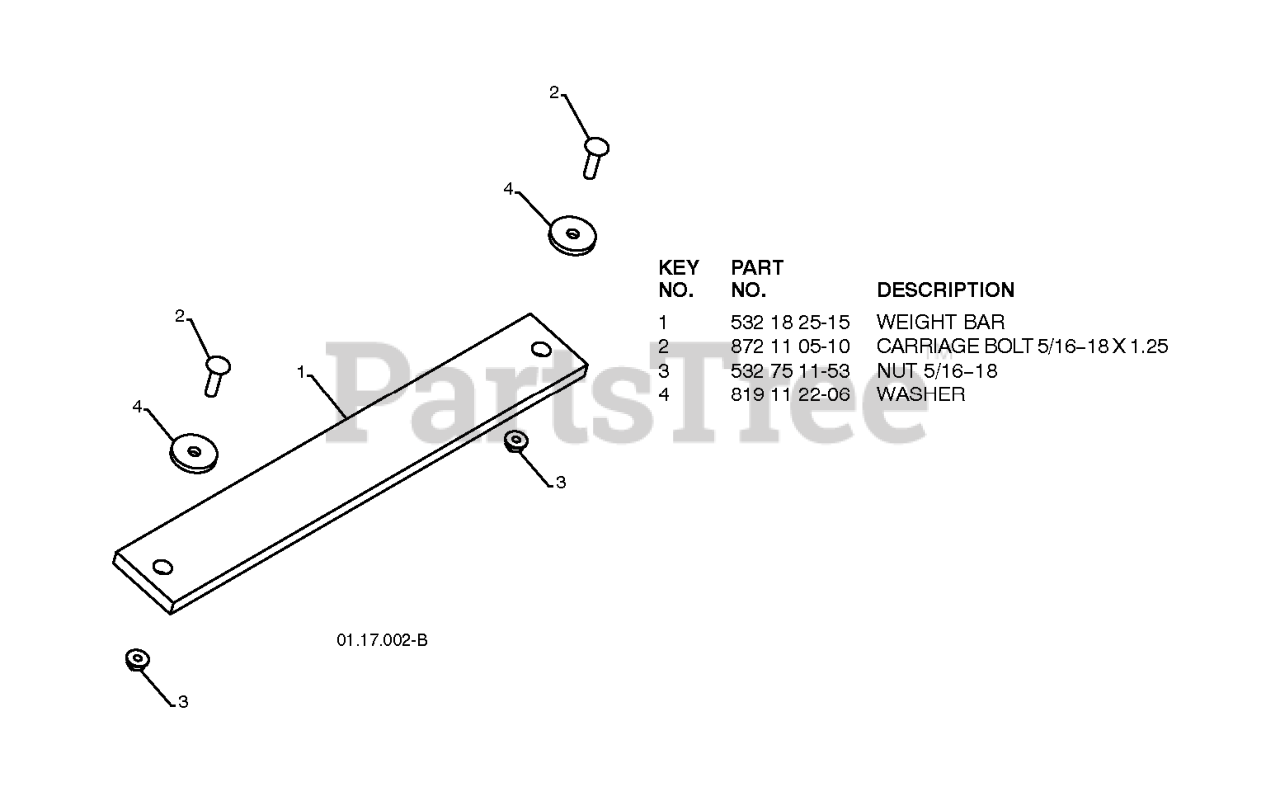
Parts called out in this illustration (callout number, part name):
1	WEIGHT,AUGER HOUSING 27 (2 2MC
2	BOLT.CARRIAGE.5/16-18
3	NUT.LOCK.5/16-18
4	WASHER.FLAT.34X1.38X22
